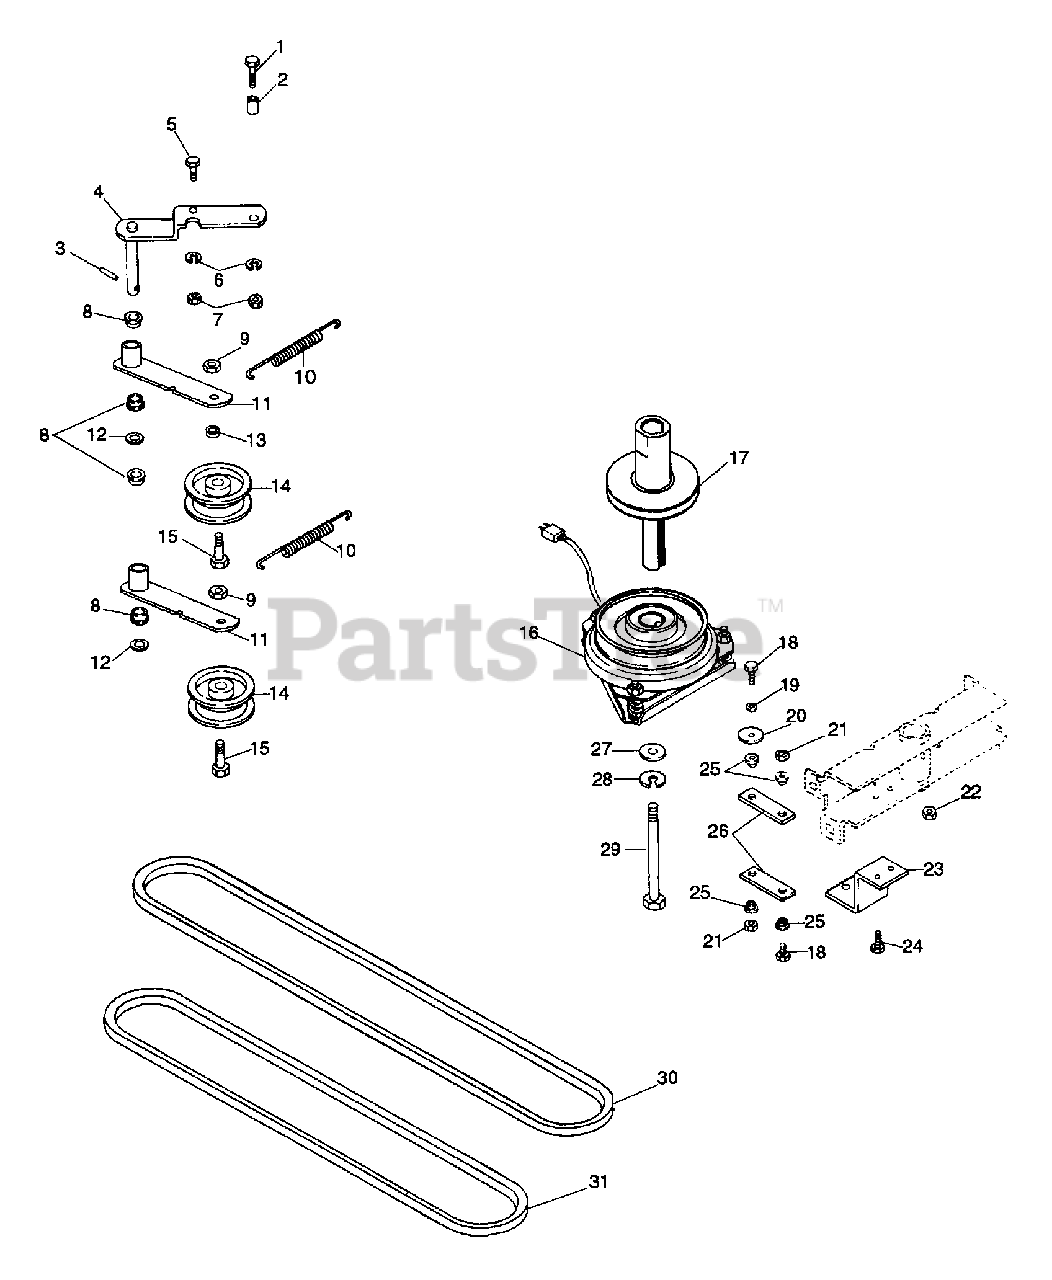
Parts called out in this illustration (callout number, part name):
1	BLT-HEX .31-18X1.50 PL GR2
2	SPACER .344X.500X.875
3	PIN-ROLL .188X1.00
5	BLT-HEX .31-18X1.00 PL GR5
6	WSHR-LK .312X.097 PL HVY
7	NUT-HEX .312-18
8	BSHG-FLG.500X.625X.312X.750NY
9	NUT-LK TOP .375-16 GR C YWZC
10	SG-TENS .085X.60X5.13 WLD8.3
11	IDLER ARM
12	WSHR-FL-STL .520X.827X.062 YZ
13	BSHG-SLV .377X.624X.235
14	IDLER - 2.25X.87
15	BLT-HEX .38-16X1.50 PL GR5
16	ELECTRIC CLUTCH
17	EXTENSION SHAFT
18	BLT-HEX 10-24X1.00 PL GR2
19	WSHR-FL-STL .194X.492X.047 PL
20	WSHR-FL-STL .281X1.250X.048PL
21	NUT-LK TOP 10-24 PL
22	NUT-LK-NYL .250-20 PL
23	TORQUE BRACKET
24	BLT-HEX .25-20X.75 PL GR5
25	SPECIAL WASHER
27	WSHR-FL-STL .463X1.375X.250 PL
28	WSHR-LK .438X.133 HVY
29	BLT-HEX .44-20X5.50 PL GR5
30	V-BELT, SAE 380-RAW EDGE
31	V-BELT, 5L-RAW EDGE
